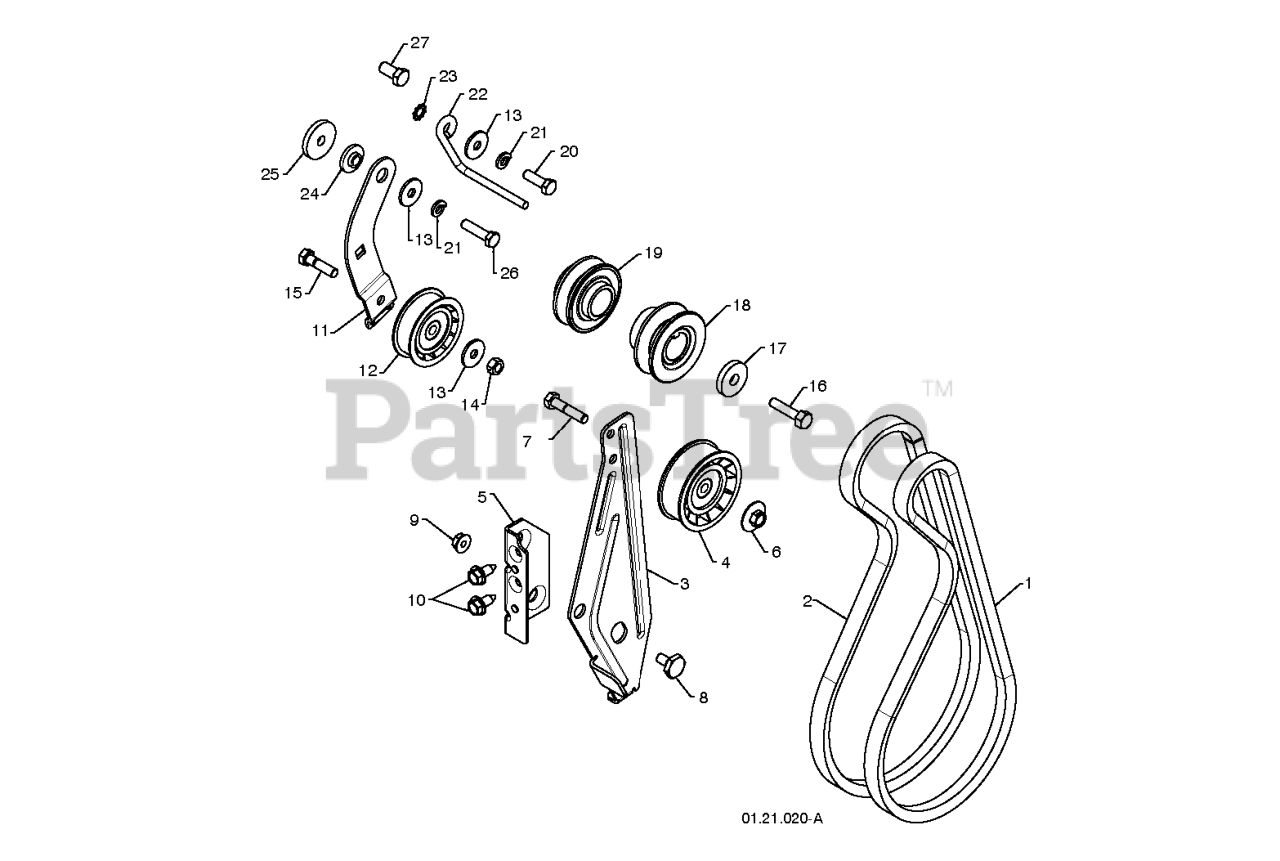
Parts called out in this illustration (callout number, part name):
1	V-BELT.IMPELLER
2	TRACTION BELT
3	ARM.IDLER.BRAKE.
4	PULLEY.W/SPACER.2.75
5	RP BRACKET.IDLER.PIVOT
6	NUT.FLANGE.HEX.5/16X18.BLACK
7	HEX BOLT
8	BOLT.SHOULDER.1/2X12
9	NUT.LOCK.5/16-18
10	BOLT.HEX.HD.WASHER.5/16-18X.75
11	RP ARM.ASM.TRACTION.IDLER
12	PULLEY.W/SPACER.2.25
13	STEEL WASHER
14	NUT.71038.31-18.HEX.NYLOCK
15	BOLT.5/16-18X1-1/4 FULL.THREAD
16	SCREW, HEX HD 3/8-24 X 1-3/8
17	WASHER.400X1.25X5.
18	PULLEY ENG IMPELLER
19	PULLEY.ASM.ENG.TRACTION.1.00
21	WASHER.LOCK.HVY.HLCL.SPR.5/16
22	BELT.GUIDE.RH
23	WASHER EXT TOOTH LOCK 5/16
24	RP BUSHING, IDLER PIVOT
25	WASHER.FLAT.34X1.38X22
